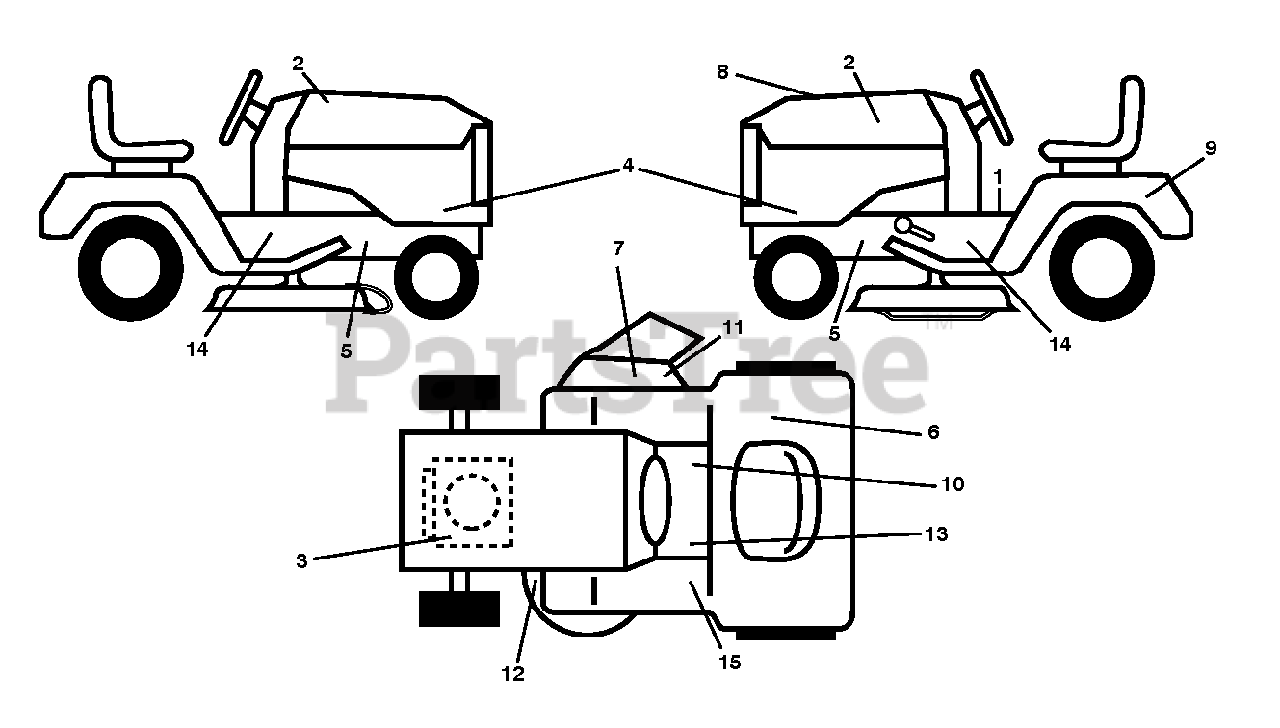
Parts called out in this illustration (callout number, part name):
1	LABEL
2	RP.DECAL.BADGE.170MM.TEXTLOGO
3	DECAL
6	Decal, Fender 100 DB/CE
7	DECAL.INTERNATIONL.CUTFINGER
8	Decal, Replacement KHSV470 TLW 42 K46
9	DECAL BTRY SYMBOLS
10	DECAL PARK BRAKE
11	DECAL, DEFLECT WARNING
12	DECAL V BELT SCHEMATIC
13	DECAL
15	DECAL
